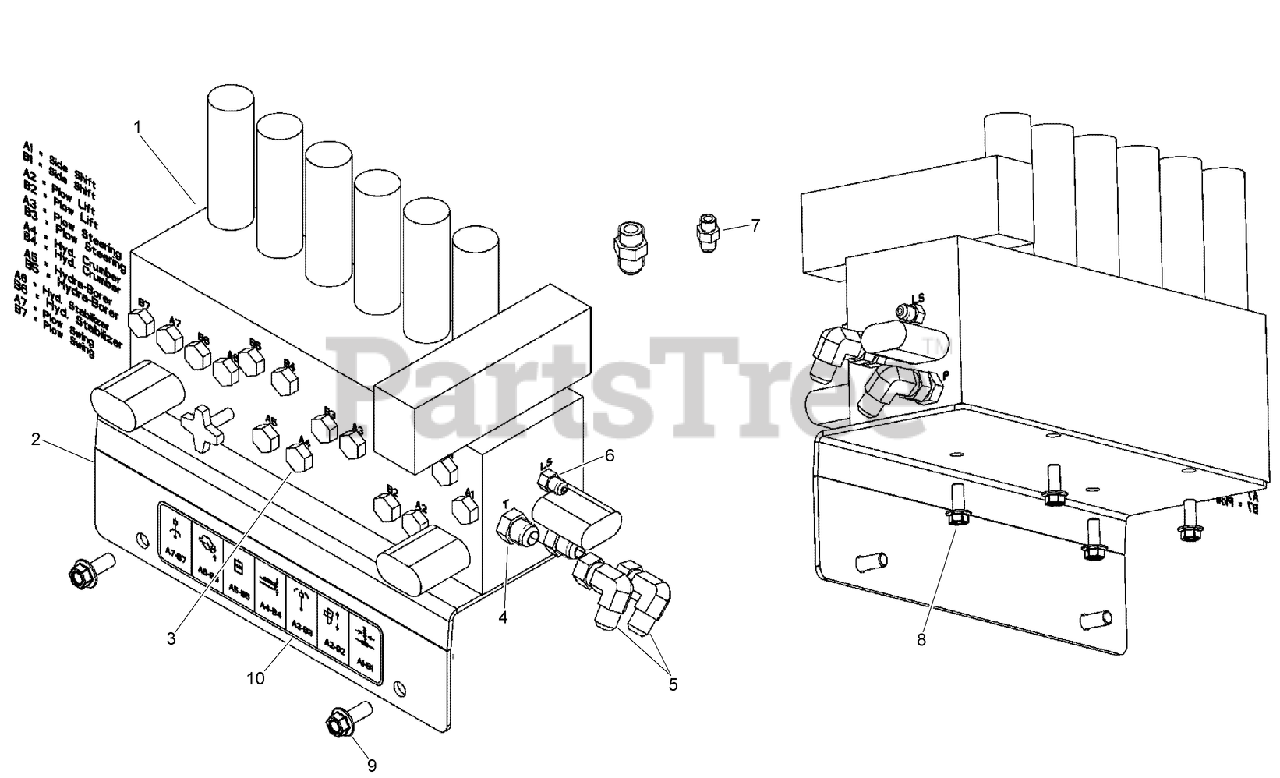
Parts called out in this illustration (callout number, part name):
1	VALVE - HIC, Auxiliary
2	PLATE - Valve Mount
3	PLUG-HEX HD
4	CONNECTOR-Str Thd 5/8, 37FL-ORB 5/8
5	ELBOW-90 Swivel 37FL 5/8 Tube
6	ADAPTER-STRAIGHT
7	CONNECTOR-Str Thd 3/8, 37FL-ORB 3/8
8	SCREW-FLANGE
9	SCREW, METRIC FLANGE w/BODY-M12 x 30
10	DECAL - Control Valve Legend
